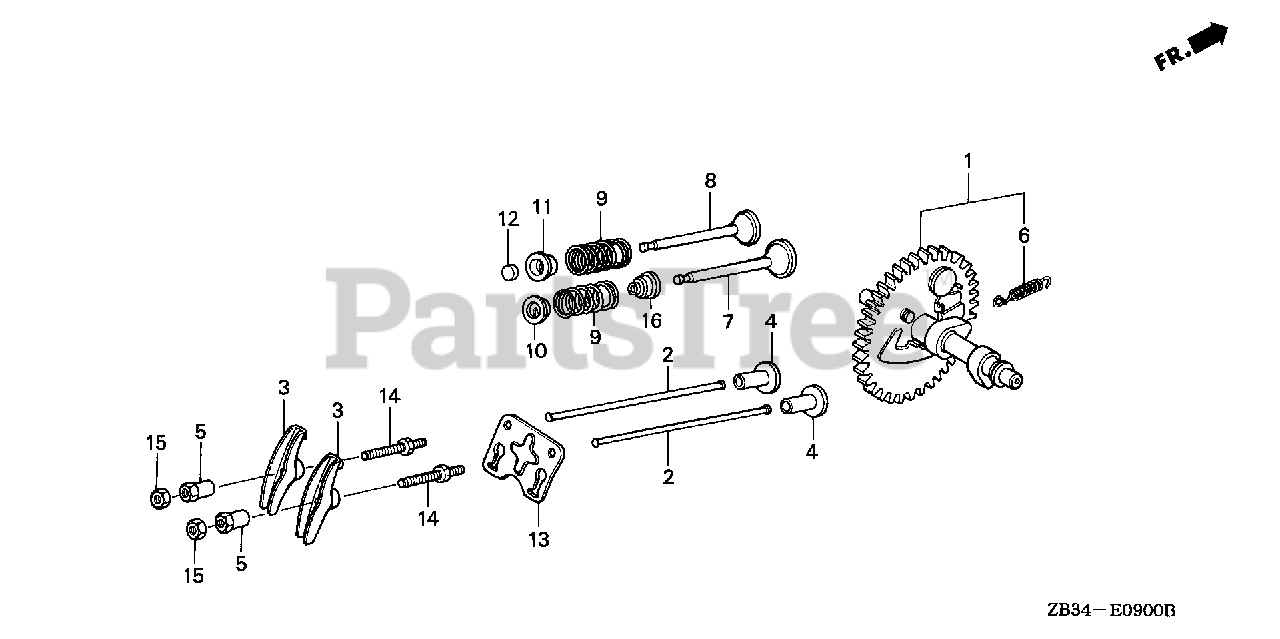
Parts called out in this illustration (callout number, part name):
1	CAMSHAFT ASSY.
2	ROD, PUSH
3	ARM, VALVE ROCKER
4	LIFTER, VALVE
5	PIVOT, ROCKER ARM
6	SPRING, WEIGHT RETURN
7	VALVE, IN.
8	VALVE, EX.
9	SPRING, VALVE
10	RETAINER, IN. VALVE SPRING
11	RETAINER, EX. VALVE SPRING
12	ROTATOR, VALVE
13	PLATE, PUSH ROD GUIDE
14	BOLT, PIVOT (8MM)
15	NUT, PIVOT ADJUSTING
16	SEAL, VALVE STEM
